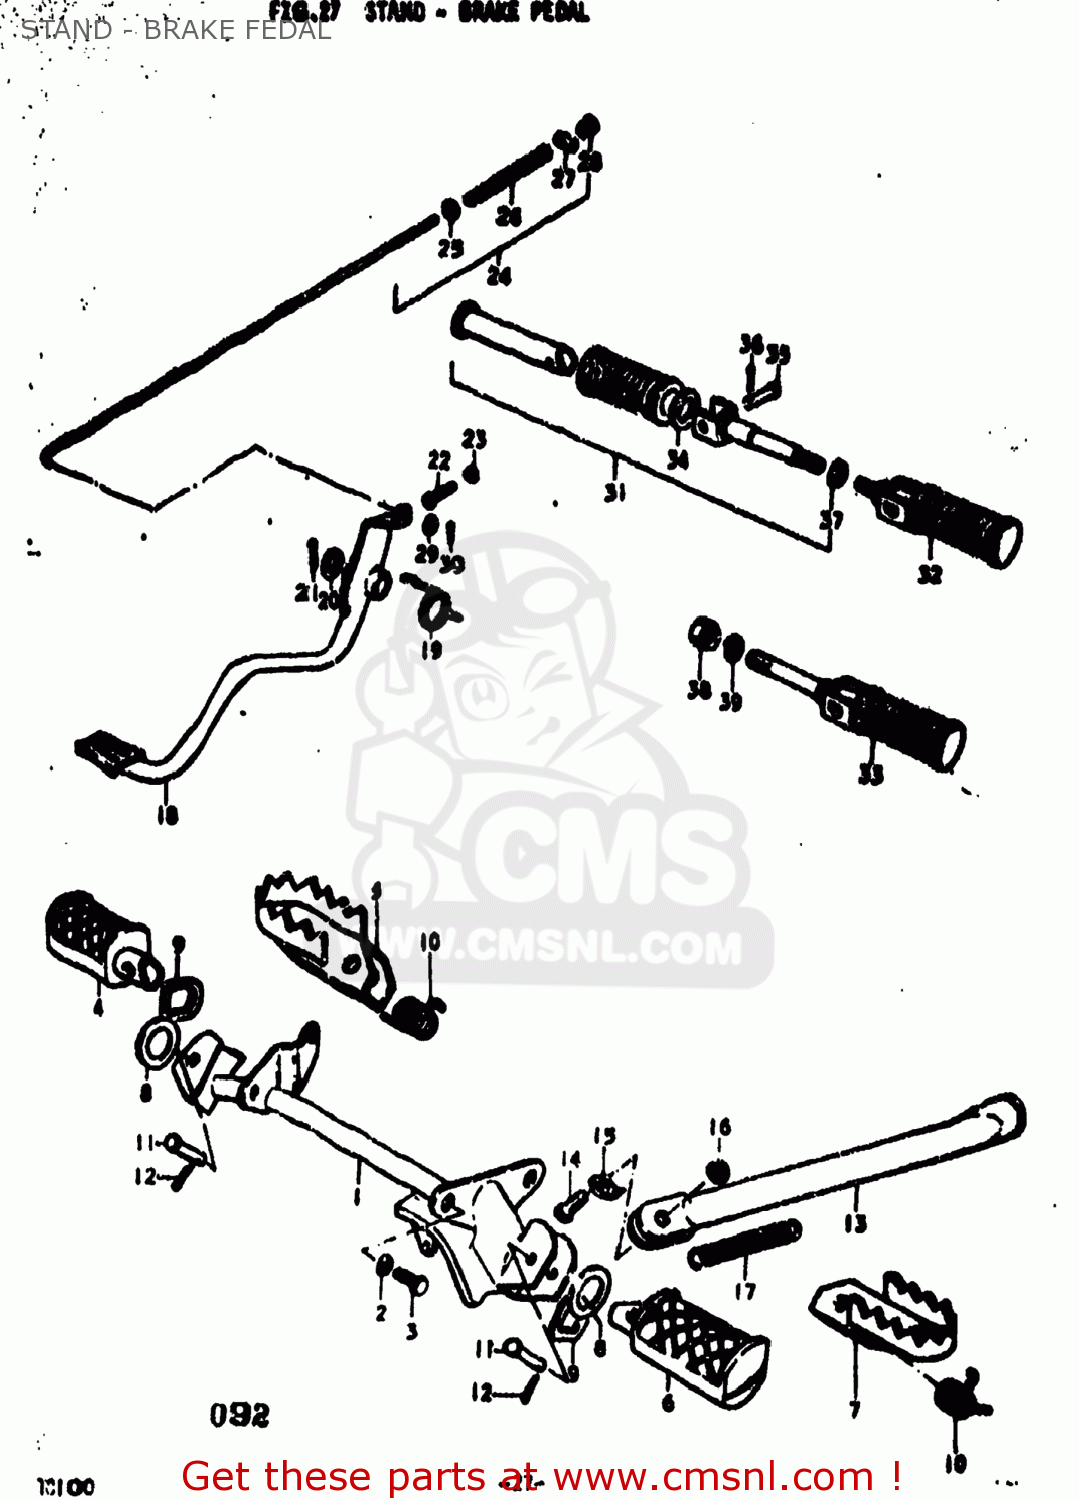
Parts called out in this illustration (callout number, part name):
1	BAR,FRONT FOOTREST
2	LOCK WASHER
3	BOLT
4	RUBBER,FOOTREST,RIGHT
5	RUBBER,FOOTREST,RIGHT
6	RUBBER,FOOTREST,LEFT
8	RUBBER,FOOTREST,LEFT
9	WASHER
10	SPRING
11	PIN
12	PIN 20X20
13	STAND,SIDE
14	BOLT(10X30)
15	WASHER
16	NUT
17	SPRING
18	PEDAL,BRAKE
19	SPRING
20	WASHER(15.5X26X2.3)
21	COTTER PIN
22	BOLT
23	NUT
24	ROD ASSEMBLY,REAR BRAKE
25	WASHER
26	SPRING
27	PIN(11X18)
28	NUT
29	WASHER
30	PIN 20X20
31	FOOTREST ASSEMBLY,REAR
32	FOOTREST ASSEMBLY,REAR
33	FOOTREST ASSY,PILLION
34	WASHER (19.5X32X2)
35	PIN
36	PIN 20X20
37	NUT
38	NUT
39	WASHER,LOCK 12
